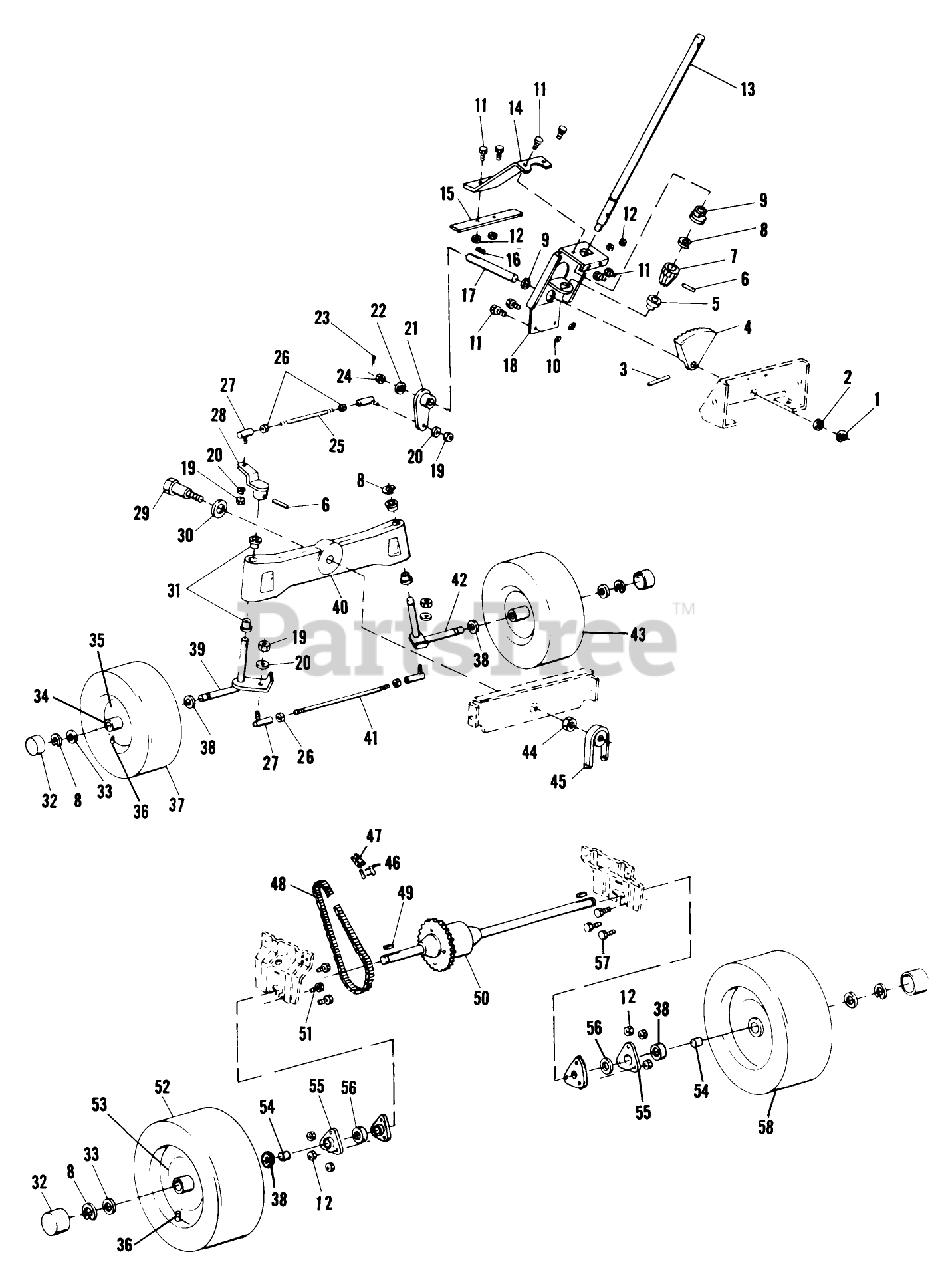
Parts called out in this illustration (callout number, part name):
6	Roll Pin
10	Speed Nut
11	Bolt 5/16-18 x
12	Nut-Nylok
14	Support Floor Pan
15	Support Brace Floor Pan
16	KEY WOODRUFF
18	Bracket, Steering Support
19	Nut 3/8-24 Nylok
20	Lockwasher
22	Washer
23	Pin-cotter 3/32 X 1/2
24	*Nut, Slotted, 1/2-20 Thd
26	Nut-3/8-24 Lt.
38	Wheel Washer
40	Front Axle Assembly
44	*Nut, Nylock, 5/8-18 Thd
50	Differential Axle Assy (See Seperate List page 3)
51	Bolt-5/16-18 x 1/4
57	Bolt-3/8-16 x 3/4
